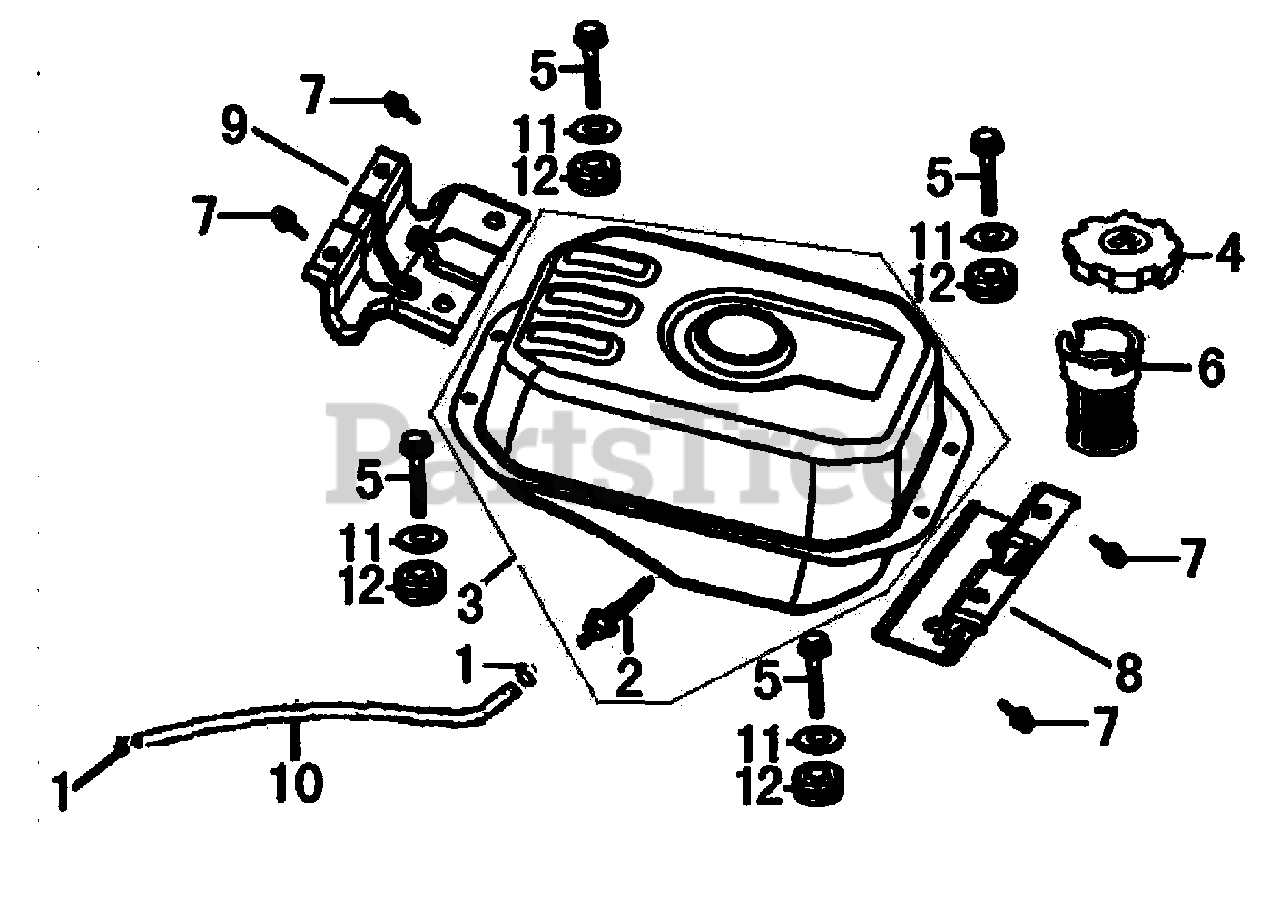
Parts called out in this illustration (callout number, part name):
1	LOOP, TUBE (CLAMP)
2	JOINT COMP., FUEL TANK
3	TANK COMP., FUEL
4	CAP COMP., FUEL FILLER
5	BOLT, HEXAGONAL
6	FILTER, FUEL
7	BOLT, FLANGE
8	HOLDER, FUEL TANK
9	HOLDER, FUEL TANK
10	TUBE, FUEL
11	WASHER, FLAT
12	CUSHION, RUBBER TANK
